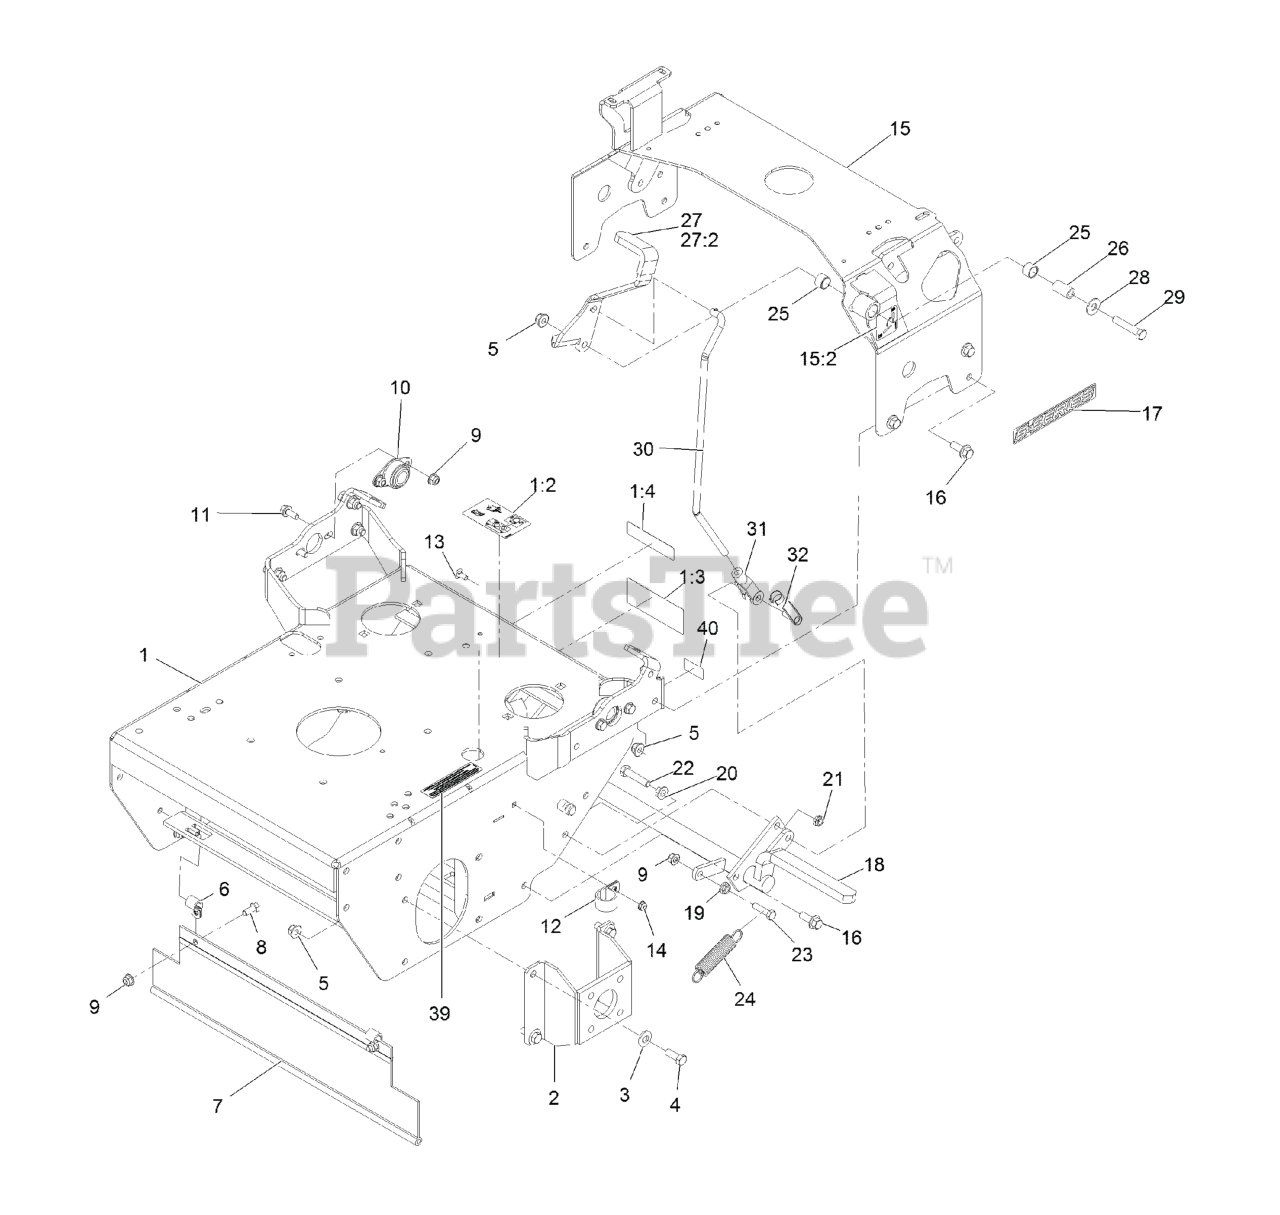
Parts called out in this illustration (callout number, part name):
1	ASM, ENGINE DECK W/ DECAL
1:2	DECAL-DRIVE RELEASE
1:3	DECAL-WARNING, SULKY
1:4	DECAL-WARNING
2	WLD,MOTOR MOUNT 48&52
3	WASHER-BELLEVILLE
4	SCREW-HH
5	NUT-HF, NI
6	CLIP-LOOM
7	SHIELD-DRAG
8	SCREW-HH
9	NUT-HF, NI
10	BEARING-FLANGE, SIDE
11	SCREW-HHF
12	CLIP-LOOM
13	SCREW-CARR
15	ASM, TANK SUPPORT W/ DECA
15:2	DECAL-PARK BRAKE, CE
16	SCREW-HHF 3/8-16 X 1
17	DECAL-S-SERIES
20	NUT-HHF, WHIZ
22	SCREW-HH
23	SCREW-HH
24	SPRING-IDLER
25	SLEEVE-BUSHING
26	BUSHING-PIVOT
27	ASM, BRAKE LEVER W/ GRIP
27:2	GRIP-LEVER
28	WASHER-FLAT
29	SCREW-HH
30	LINKAGE, BRAKE
31	YOKE-LINKAGE, BRAKE
32	PIN-SPRING, CLEVIS
39	DECAL-ARRESTOR, SPARK
40	Decal-Patent Ttco.Com
